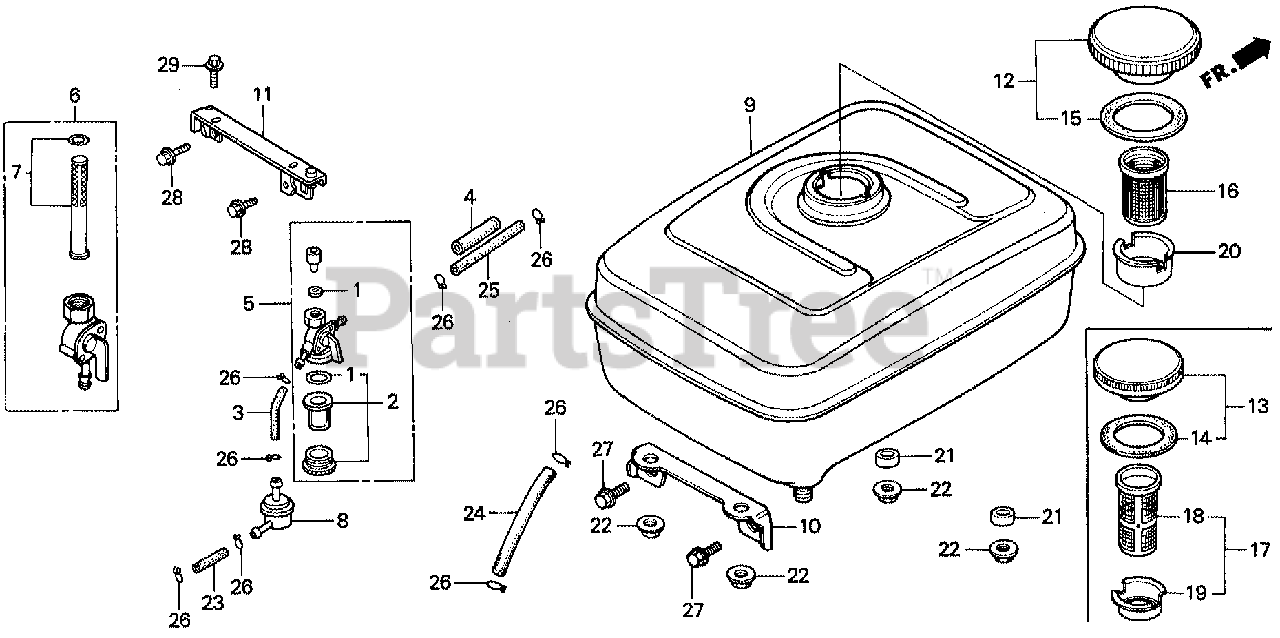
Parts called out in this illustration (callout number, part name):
6	PETCOCK ASSY.
7	SCREEN SET
9	TANK, FUEL *R8* (BRIGHT RED)
10	STAY, FUEL TANK
12	CAP, FUEL FILLER
15	GASKET, FUEL FILLER CAP
16	FILTER, FUEL
20	HOLDER, FUEL FILTER
22	NUT, FLANGE (8MM)
24	BULK HOSE, FUEL (4.5X3000) (4.5X80)
26	CLIP, TUBE (B8)
27	BOLT, FLANGE (8X16)
